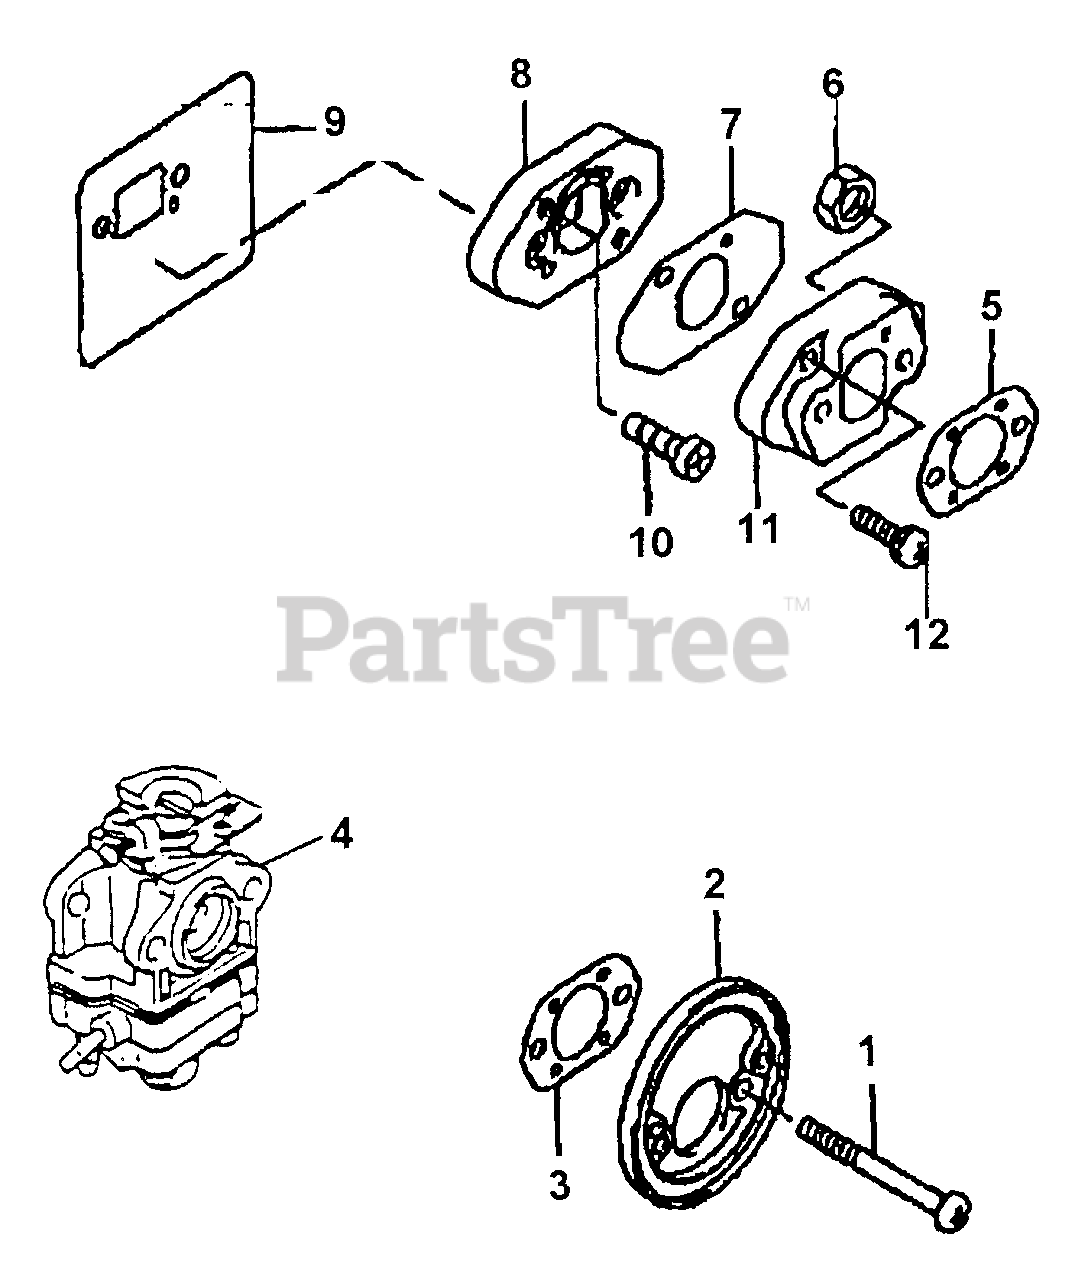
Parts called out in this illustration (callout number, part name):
1	SCREW
2	BASE, AIR CLEANER
4	CARBURETOR
8	ADAPTER, INSULATOR
10	SCREW
11	INSULATOR
12	SCREW
